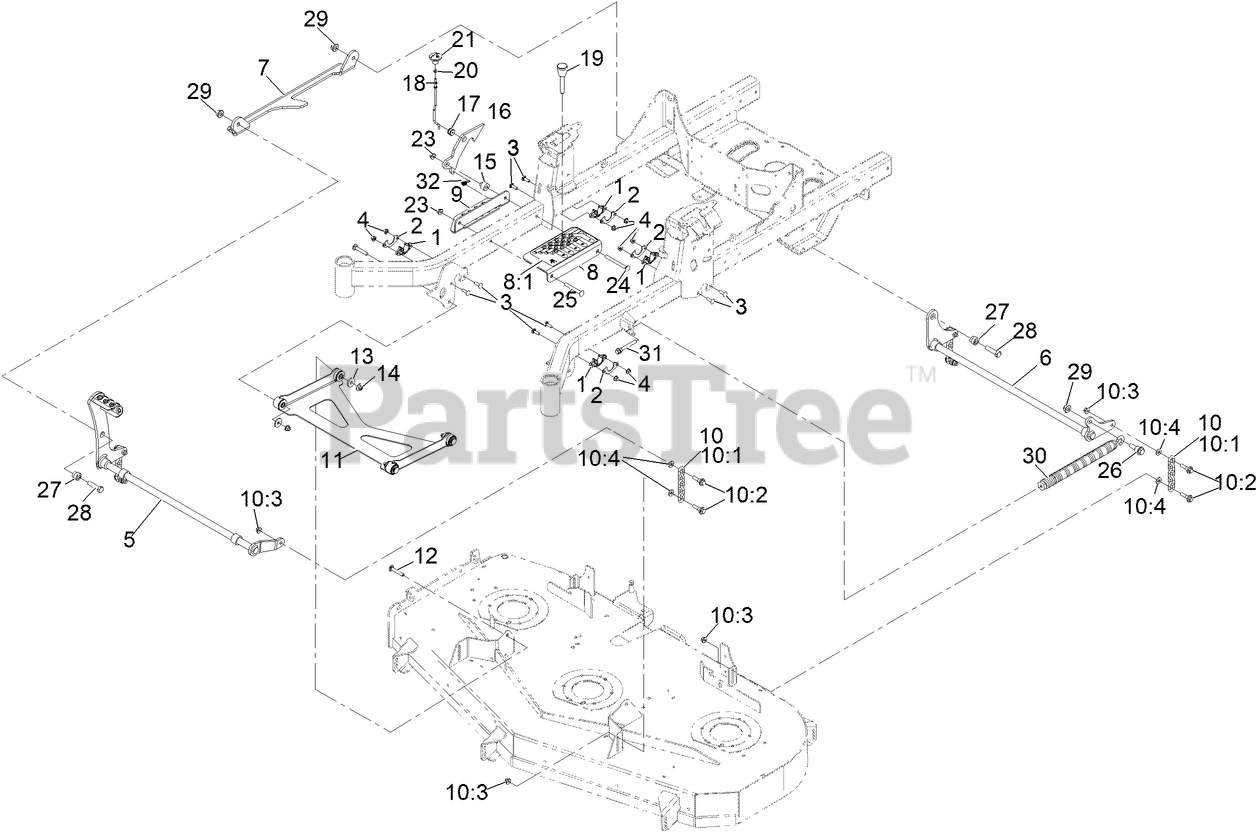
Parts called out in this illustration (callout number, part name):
1	BEARING-FLANGE
2	GUSSET-LIFT, DECK
3	SCREW-CARR
4	NUT-HF, NI
5	SHAFT-DECKLIFT FRONT
6	SHAFT-DECKLIFT REAR
7	LINK-DECKLIFT
8	BRACKET ASM
8:1	DECAL-HOC
9	Plate, HOC Lower
10	DECK CHAIN ASM
10:1	CHAIN-LIFT, DECK
10:2	BOLT-SHOULDER
10:3	NUT-HF, NI
11	DECK STRUT ASM
12	BOLT-CARR, SHORT NECK
14	Nut-Nyloc 3/8-16 Flg
15	SPACER-STEPPED
16	LATCH, TRANSPORT
17	GROMMET
18	LINKAGE, TRANSPORT
19	PIN-HOC
20	NUT-JAM
23	NUT-HF, NI
24	SCREW-CARR
25	SCREW-CARR
26	SCREW-SHOULDER HHF
27	SPACER, HOC
28	SCREW-HEX
29	NUT-HF, NI
30	SPRING-EXTENSION
31	BOLT-SHOULDER
32	SPRING, EXTENSION
